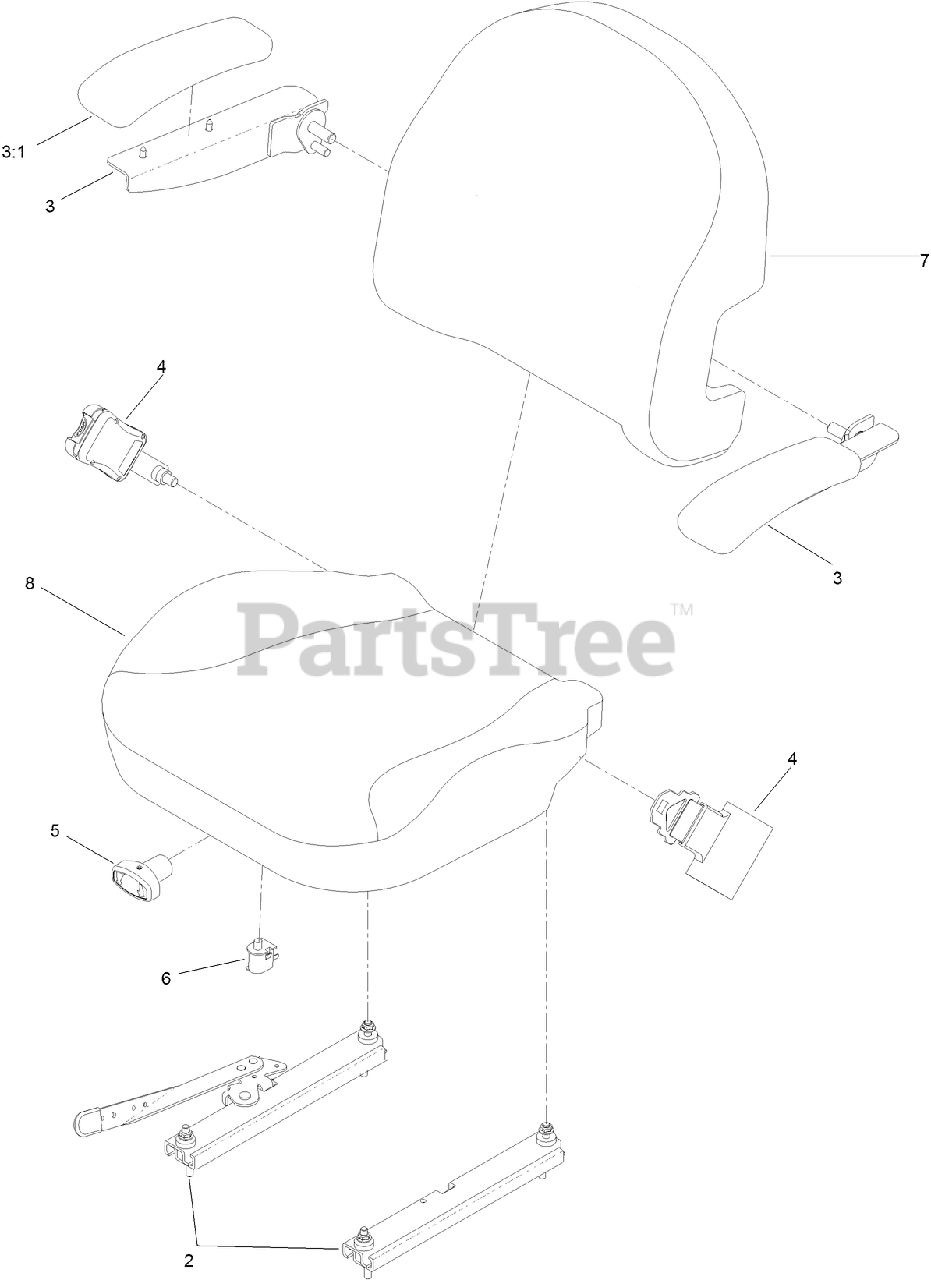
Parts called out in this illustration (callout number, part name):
2	TRACK SET
3	ARMREST KIT
3:1	CUSHION-REST, ARM
4	SEAT BELT KIT
5	KNOB-ADJUSTER
6	SWITCH-BAIL
7	COVER-BACK
8	COVER-CUSHION
